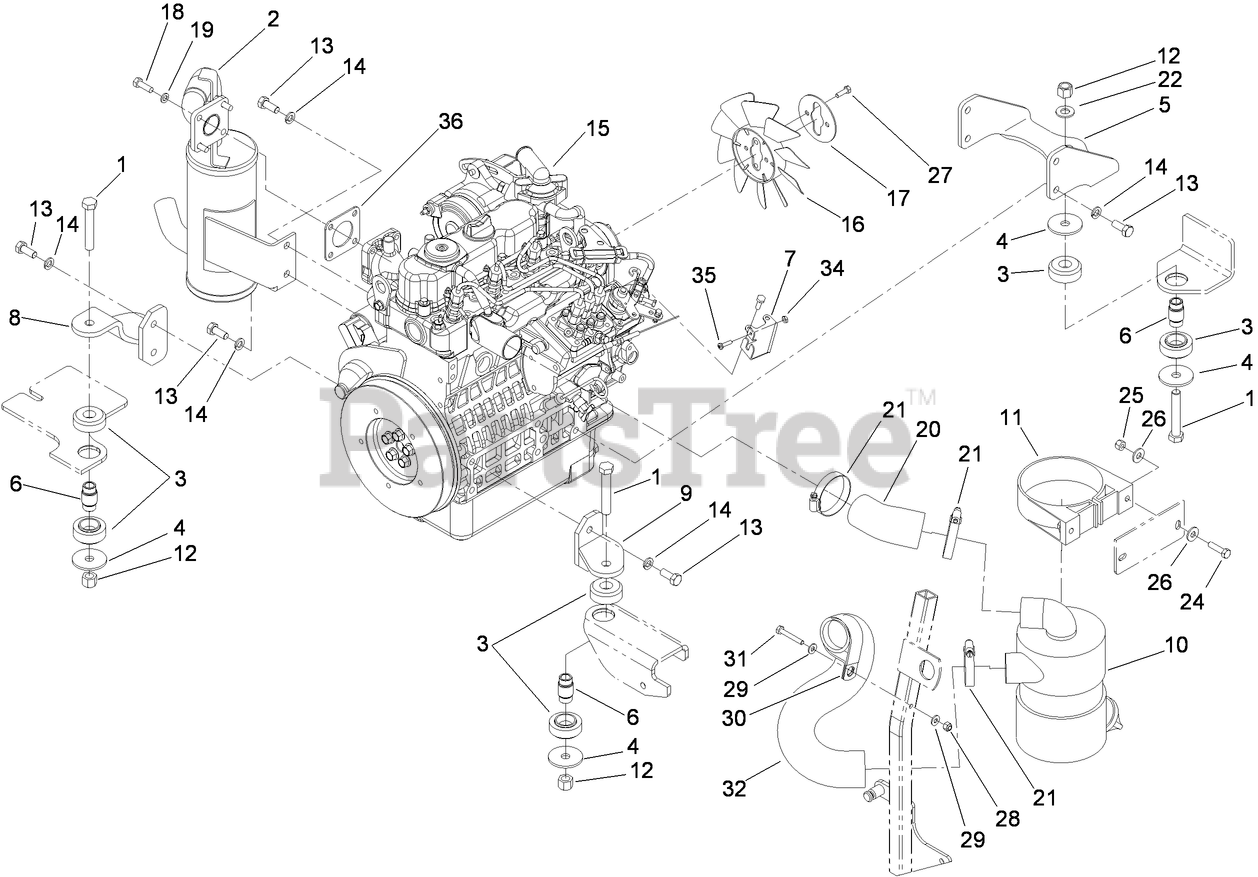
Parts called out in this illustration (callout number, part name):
1	SCREW-HH
2	MUFFLER
3	MOUNT-ISOLATION ASM
4	WASHER-LARGE
5	BRACKET-ENGINE MOUNT, REAR
6	SPACER
7	BRACKET-SUPPORT, THROTTLE
8	SUPPORT-ENGINE, RH
9	SUPPORT-ENGINE, LH
10	AIR CLEANER ASM
11	BRACKET-MOUNTING
12	NUT-LOCK, NI
13	SCREW-HH
15	ENGINE-KUBOTA DSL
17	PLATE-REATAINER, FAN
18	SCREW-HH
19	SCREW-HH
20	HOSE-INTAKE, AIR CLEANER
21	CLAMP-HOSE
22	WASHER-FLAT
24	SCREW-HH
25	NUT-LOCK, NI
26	WASHER-PLAIN
27	SCREW-HH
28	NUT-LOCK, NI
29	WASHER-FLAT
30	CLIP-LOOM
31	SCREW-HH
32	HOSE-INTAKE, ENGINE
34	NUT-HEX
35	SCREW-TORX
36	GASKET-MUFFLER
